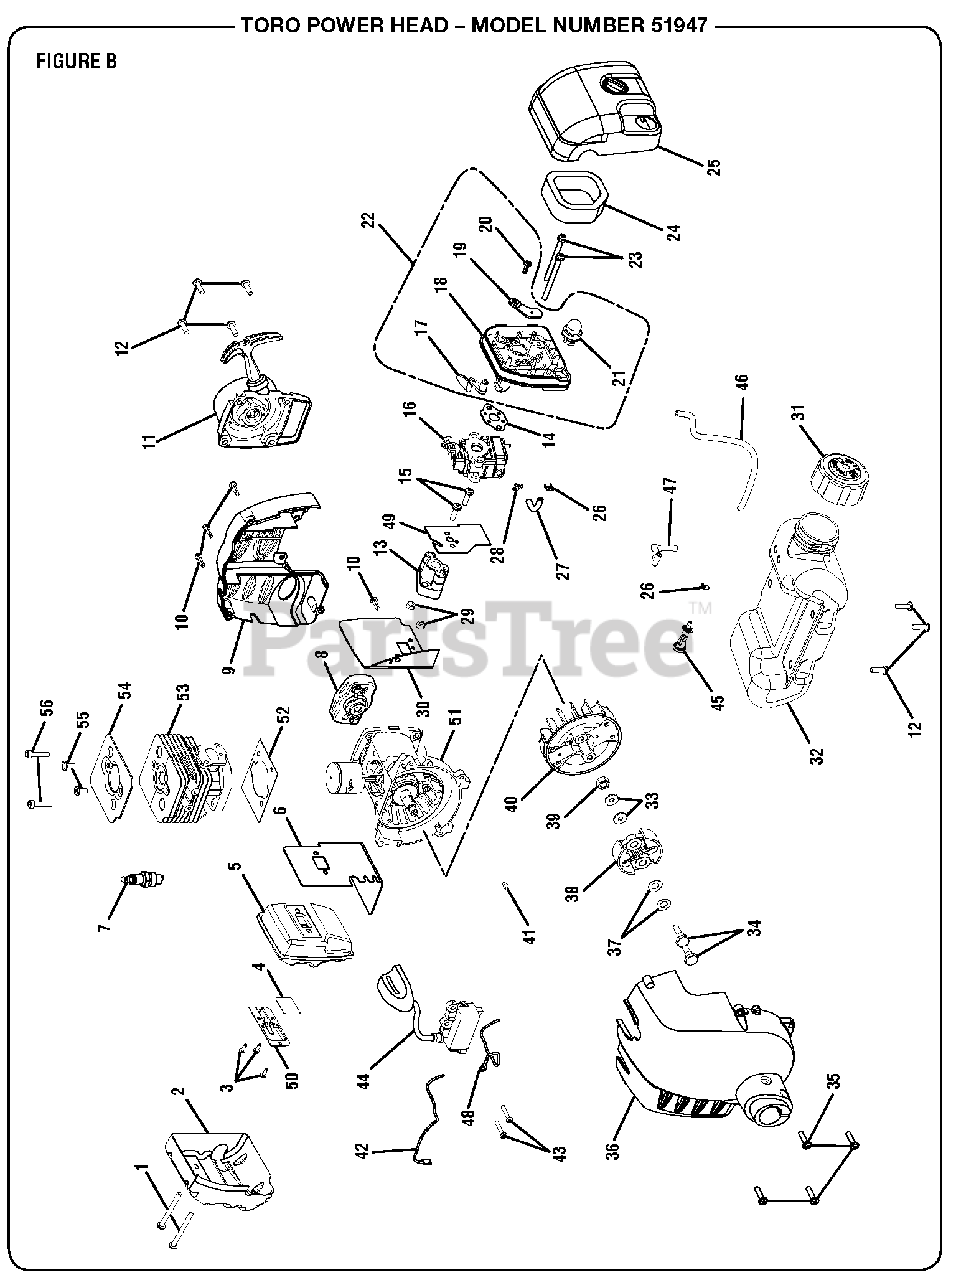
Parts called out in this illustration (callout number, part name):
1	Screw (M5 x 50 mm, Torx Slotted Recessed Pan Hd.)
2	Heat Shield
3	Screw Recess Pan Hd.)
4	Screen
5	Muffler Assembly
6	Muffler Gasket
7	Spark Plug (RCJ4Y)
8	Starter Cup
9	Engine Housing, Rear
10	Screw (M4 x 16 mm, Torx Recessed Pan Hd.)
11	Starter Recoil Assembly
12	Screw (m5 x 16 mm, Torx Slotted)
13	Heat Dam Insulator
14	Carburetor Gasket
15	Screw (M5 x 31 mm Torx Slotted Recessed Pan Hd.)
16	Carburetor Assembly
17	Choke Lever
18	Carburetor Plate
19	Choke Plate
20	Screw (M4 x 12 mm, Slotted Recessed Pan Hd.)
21	Primer Assembly
22	Filter Housing Assembly
23	Screw (M5 x 60 mm, Slotted Recessed Pan Hd. Machine)
24	Element
25	Cover Assembly
26	Hose Clip
27	Fuel Line (45 mm)
28	Hose Clip
29	Nut (M5 x .8 mm)
30	Insulator Gasket
31	Fuel Cap Assembly
32	Fuel Tank and Cap Assembly
33	Washer
34	Clutch Screw
35	Screw (M5 x 20 mm Torx Slotted Recessed Pan Hd.)
36	Front Housing Assembly
37	Curved Washer
38	Clutch Assembly
39	Rotor Nut
41	Woodruff Key (10 mm x 3 mm)
42	Lead Wire, Black
43	Screw (M4 x 22 mm, Torx Slotted Recessed Pan Hd.)
44	Coil Boot Assembly
45	Fuel Filter
46	Fuel Line (150 mm) [LP1500]
47	Fuel Line (118 mm)
48	Lead Wire, Red
50	Trimmer Outlet
51	Crankcase Assembly
53	Cylinder
54	Cylinder Plate
55	Screw (M5 x 10 in., Torx Recessed Pan Hd.)
56	Screw (M5 x 22 mm, Soc. Hd.)
